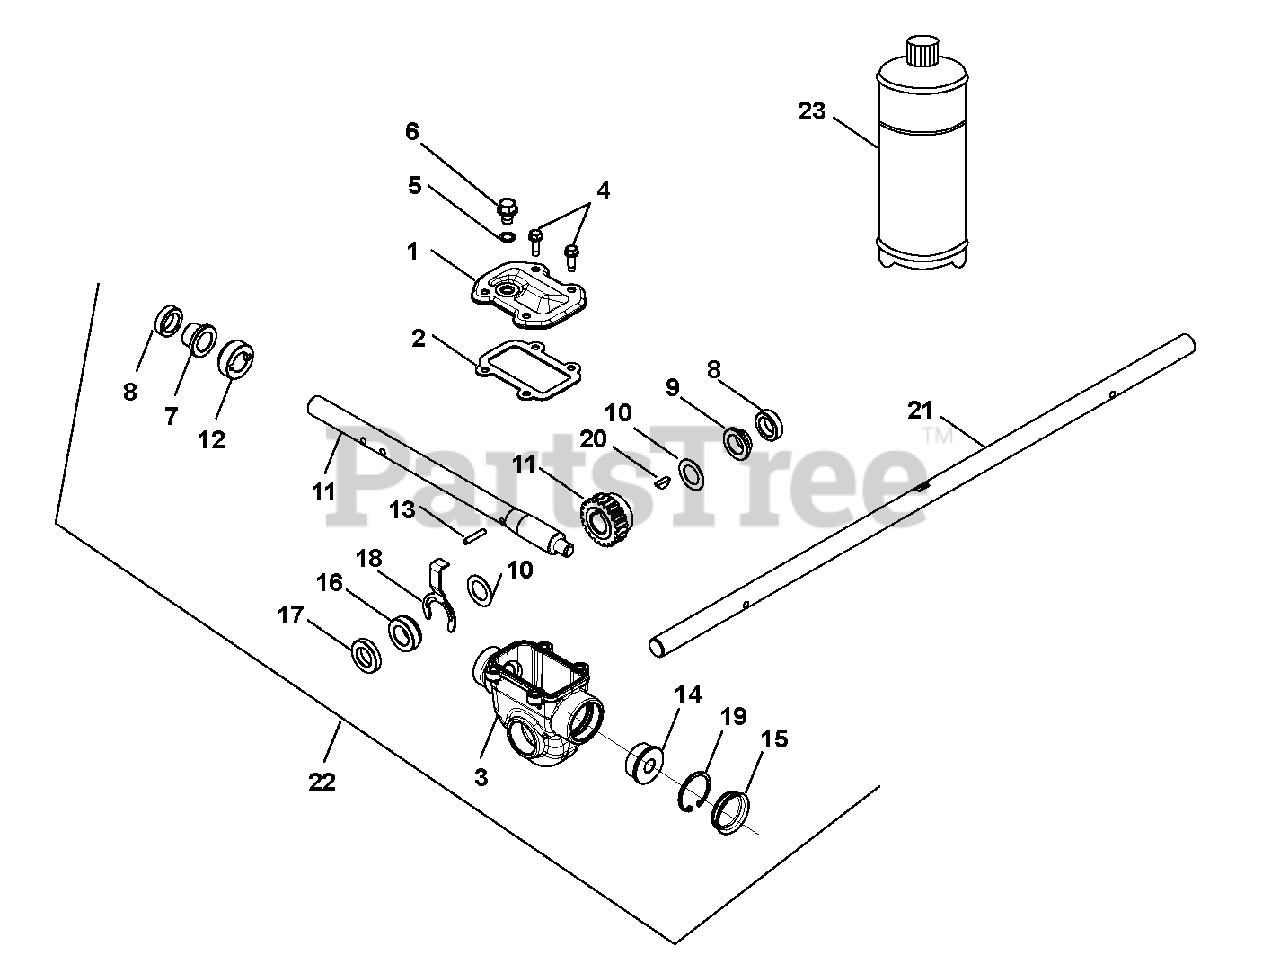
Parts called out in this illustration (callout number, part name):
1	COVER, TOP - COMPACT
2	GASKET, TOP - COMPACT GEARCASE
3	GEARCASE, COMPACT ALUMINUM
4	SCR-TAP .25-20X.75 HWH TR YWZ
5	WSHR-BND-SEAL .38X.75X.11 GALV
6	@SCR-ROLOK .38-16X.50 HWH YWZC
7	BSHG-FLG .755X.878X.75X1.25
8	SEAL-OIL .748X1.125X.312 TB2-H
9	BSHG-FLG .755X.878X.424X1.25
10	WSHR-FL-STL .760X1.225X.032 YZ
11	SHAFT AND WORM GEAR ASSEMBLY
12	THRUST COLLAR, .75" ID SLIPFIT
13	PIN-STR .188X1.00 6150
14	BSHG-FLG .503X1.303X.62X1.465
15	COVER, GEAR CASE 1.50"
16	BSHG-FLG COMPACT, RIGHT
17	SEAL-OIL .748X1.300X.250 TB2-H
18	BUSHING RETAINER, COMPACT
19	RG-RTNG-INT 1.500X.050
20	KEY-WDRF .19X.63 HRD #61
21	SHAFT, RAKE-28" (.750 DIA)
22	GEAR CASE, 24" ALUM SM TOP-LD
23	ARIENS L3 LUBE, 8 OZ BOTTLE
